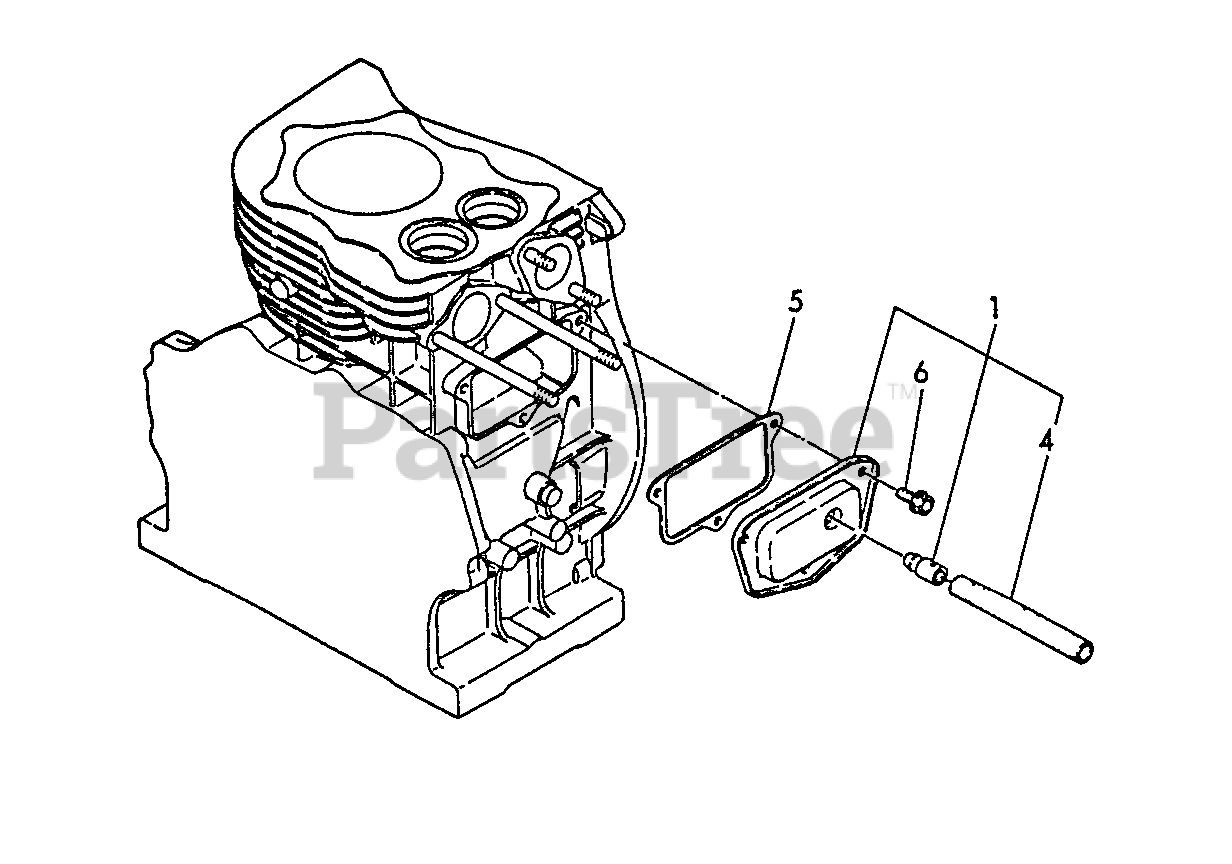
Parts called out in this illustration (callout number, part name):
1	BREATHER ASSY
4	PIPE, BREATHER
6	BOLT - 6×8 -- PLATED
